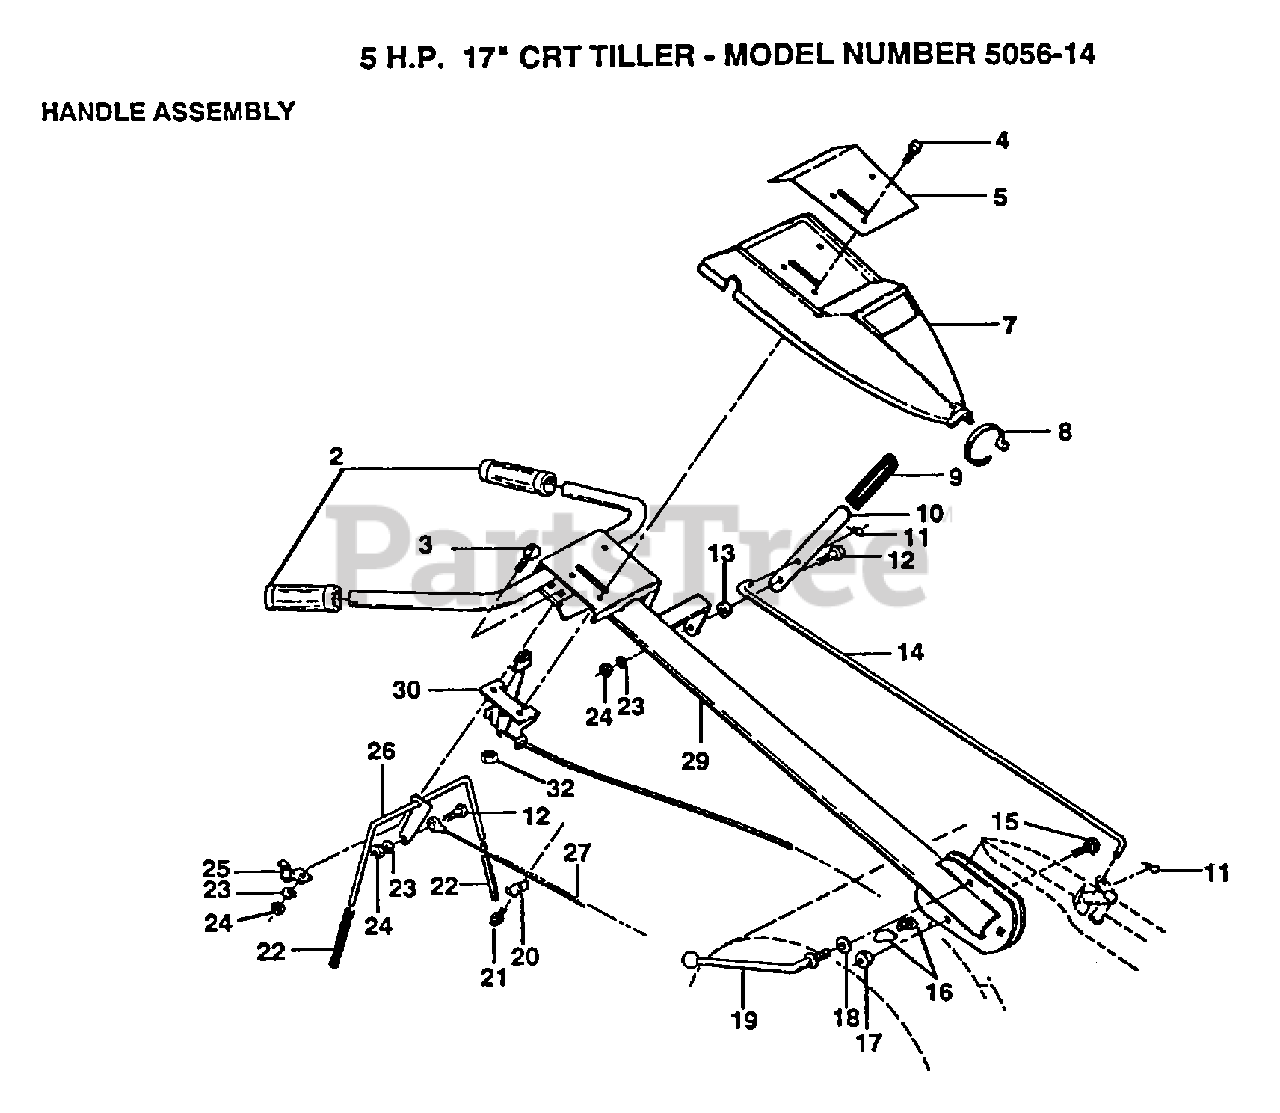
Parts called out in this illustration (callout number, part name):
3	BOLT
4	SCREW
7	"PANEL,CONT TI"
8	TIE CABLE CRT
9	GRIP T
10	SHIFT HANDLE CRT
11	RETAINER M
12	SHOULDER BOLT ST
13	GROMMET CRT
14	SHIFT ROD CRT
15	BOLT D
16	LOCK CRT
18	WASHER CRT
19	LEVER LOCK CRT
20	CONDIUT CLIP T
22	GRIP BAR CRT
23	LOCKWASHER
26	"ASSY CONTROL, BAR"
27	CABLE.CLUTCH.CRT
30	"CONT,THROTTLE"
